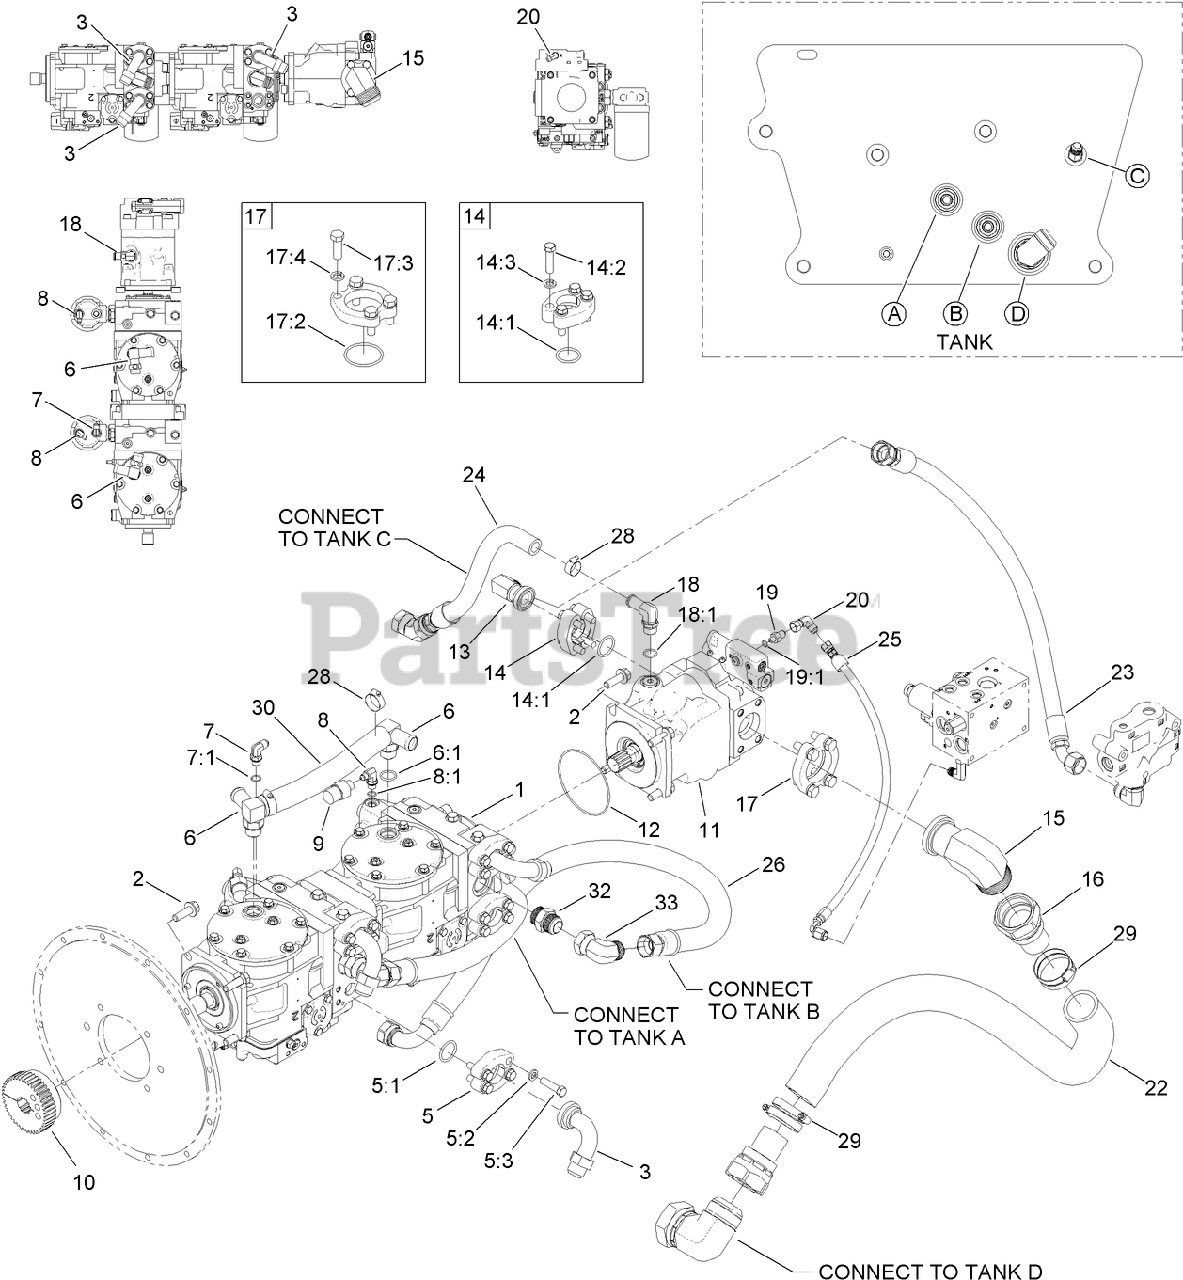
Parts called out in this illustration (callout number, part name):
1	TANDEM PUMP ASM
2	SCREW-HHF
3	FITTING-ELBOW
5	HYD FLANGE KIT
5:1	O-RING
5:2	WASHER-LOCK
5:3	SCREW-HH
6	CONNECTOR
6:1	O-RING
7	FITTING-ELBOW, 90 DEG
7:1	O-RING
8	FITTING-ELBOW, 90
8:1	O-RING
9	SWITCH-PRESSURE
10	HUB-COUPLER
11	HYD PUMP ASM
12	SEAL-O RING
13	ADAPTER-FLANGE, SPLIT
14	FLANGE KIT
14:1	O-RING
14:3	WASHER-LOCK
15	ADAPTER-FLANGE, SPLIT
16	FITTING-STRAIGHT
17	FLANGE KIT
17:2	O-RING
17:3	SCREW-HH
17:4	WASHER-LOCK
18	FITTING
18:1	O-RING
19	ADAPTER-STRAIGHT
19:1	O-RING
20	ELBOW-SWIVEL, 90 DEG
22	HOSE-FUEL, TANK FILL
23	HYD HOSE ASM, HP
24	HYD HOSE ASM, LP
25	HYD HOSE ASM
26	HYD RETURN HOSE ASM
28	CLAMP-HOSE
29	CLAMP-HOSE
32	FITTING-STRAIGHT
33	FITTING-ELBOW, 90
